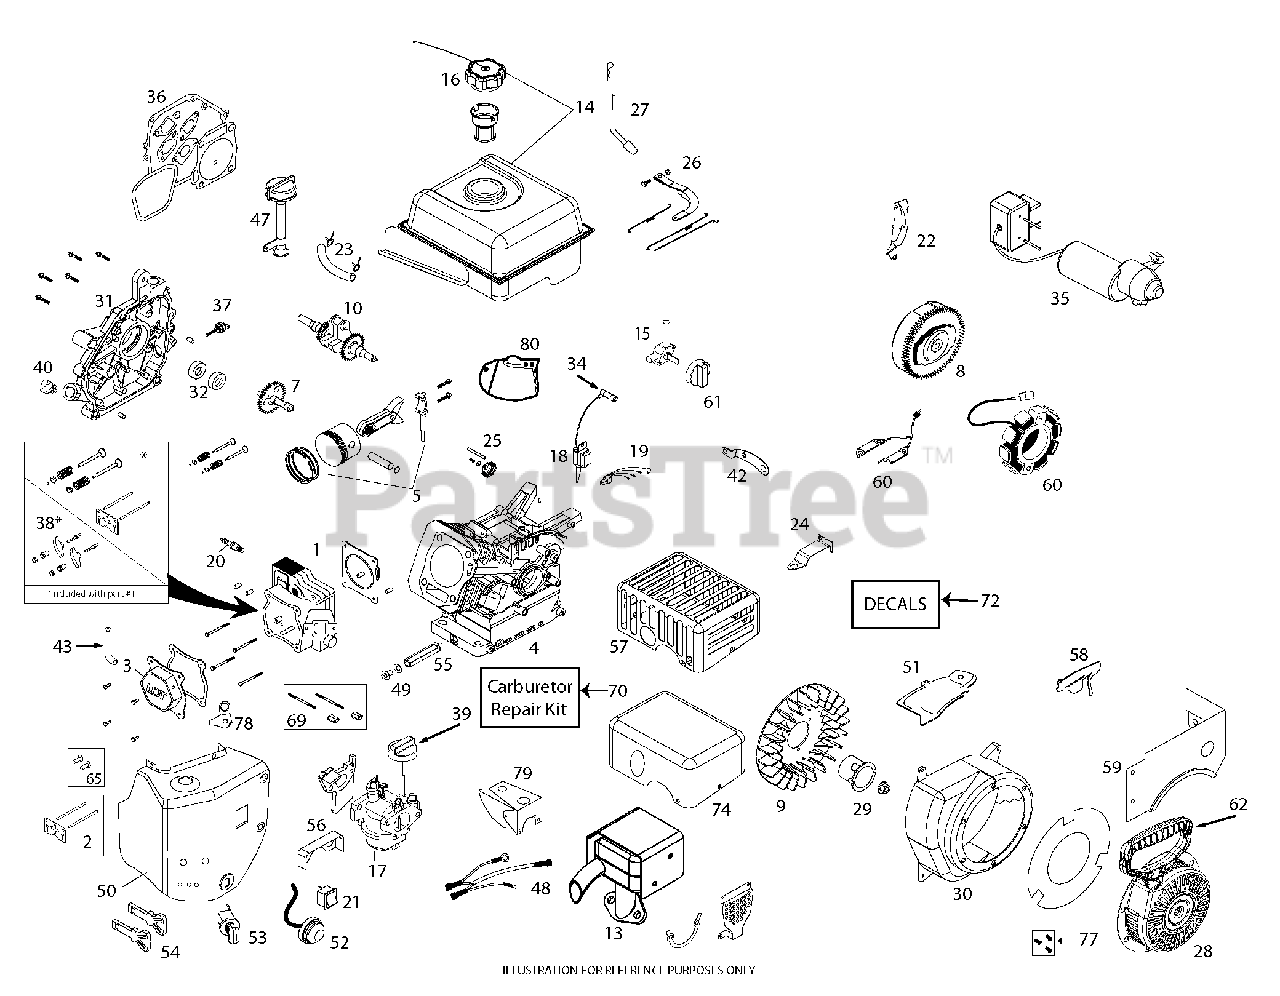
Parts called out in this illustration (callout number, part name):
1	CYLINDR.HEAD.SRV.KIT
2	KIT.PUSH.ROD.SRV(SK208-1001)
3	VALVE COVER ASSEMBLY
4	CYLINDER.ASM.SKSN0001.2
5	KIT.PISTON.SRV(SK208-1400)
7	KIT.CAMSHAFT.SRV(SK208-1600)
8	208CC ELEC START FLYWHEEL
9	KIT.COOLNG.FAN.SERV(SK208-4000
13	ASSY.MUFFLER.GENII.SKSN0201.1
14	FUEL.TK.ASSY.GENII.SKSN0311.1
15	FUEL.PETCOCK.SNOW(SKSN4900)
16	FUEL CAP OVERSIZED CLICK STYLE
17	CARB.ASSEMBLY.GEN.II.LCT.208CC
18	208CC IGN COIL (STD)
20	SPARK.PLUG(2083810)
21	SWITCH.ON/OFF(SKSN-0403)
22	SHLD.ELEC.START.FLY(SKSN-0605)
23	FUEL HOSE KIT
24	SPEED.CTRL.BRKT.(SKSN0150)
25	GOVENOR.GEARS ASM(SK2082900)
26	CARBURETTOR GOVERNOR LINK.ASM.
27	KIT.GOVERNOR.CRANK(SK208-3100)
28	RECOIL.STRT.ROUND(BLK) SNOW
29	STRTER.CUP(NON-SLOT)SKSN0601.2
30	BLOWER HOUSING ASSEMBLY
30	BLOWER.HOUSING.ELEC.START.LCT
31	CRANKCASE COVER ASSY
31	COVER CRANKCASE.LCT.SK2083605
32	SEAL KIT (2 PCS)
34	SPARK.PLUG.BOOT.SNW,SKSN4691.1
35	ELEC.START.GEN2.SKSN0400.2
36	GASKET.KIT.208CC(SK2084300.1)
37	DIPSTICK SMALL
38	ROCKER ARM KIT
39	CHOKE.KNOW.SNOW(SKSN4500)
40	NON REMOVABLE PLUG
43	TUBE.BREATHER.LCT.208
47	High Oil Fill Tube Assembly
47	HIGH OIL FILL DIPSTICK ASSEM
48	WIRE.HARNESS.SNOW
49	KIT.OIL.DRAIN.PLUG(SK2089911
50	HEATER.BOX.ASY-GEN2
52	PRIMER.BULB.WITH HOSE (SNOW)
53	SWITH.KEY.ASSEM.SNOW.SINGLE.ST
54	KEY SET(2 KEYS) SKSN0407.1
55	EXTENDED OIL DRAIN TUBE
56	SHIELD.VAPOR.SNOW
57	CE COMPLAINT.MUFLR.SKSN0202.1
58	GOVERNOR.LINK.SHIELD PLATE
59	FUEL.TNK.SKRT.GENII.SKSN0103.1
60	208CC 60W ALTERNATOR
61	FUEL KNOB-SNOW
62	STARTER.GRIP.SNOW.LCT.SKSN0603
65	TAPPET.KIT.LCT.208CC
69	CARB.STUDS & COUPLING KIT.SNOW
70	CARB.REPAIR.KIT.LCT.SK9900.1
74	COVER.MUFFLER.HEAT.SHIELD.
77	BOLT.KIT.RECOIL.LCT.ALL.ENGINE
